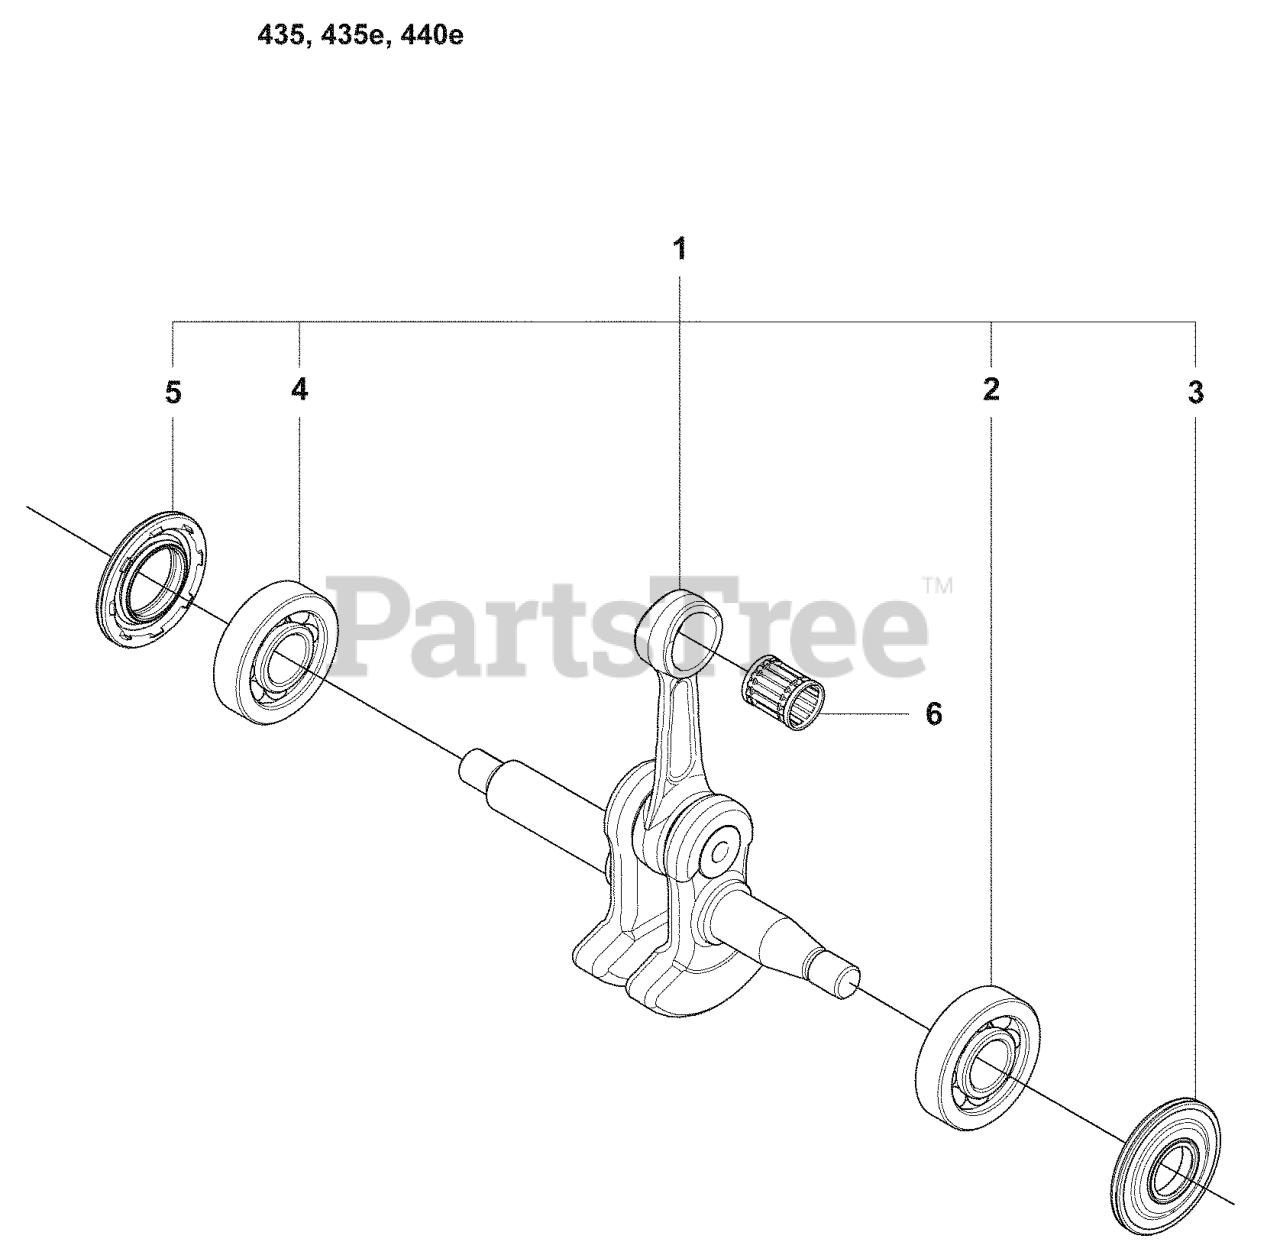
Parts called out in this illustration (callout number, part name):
1	CRANKSHAFT ASSY
2	BALL BEARING 6001 OD32
3	SEALING
4	BALL BEARING 6001 OD32W
5	SEALING
6	SUPPORT BUSHING
